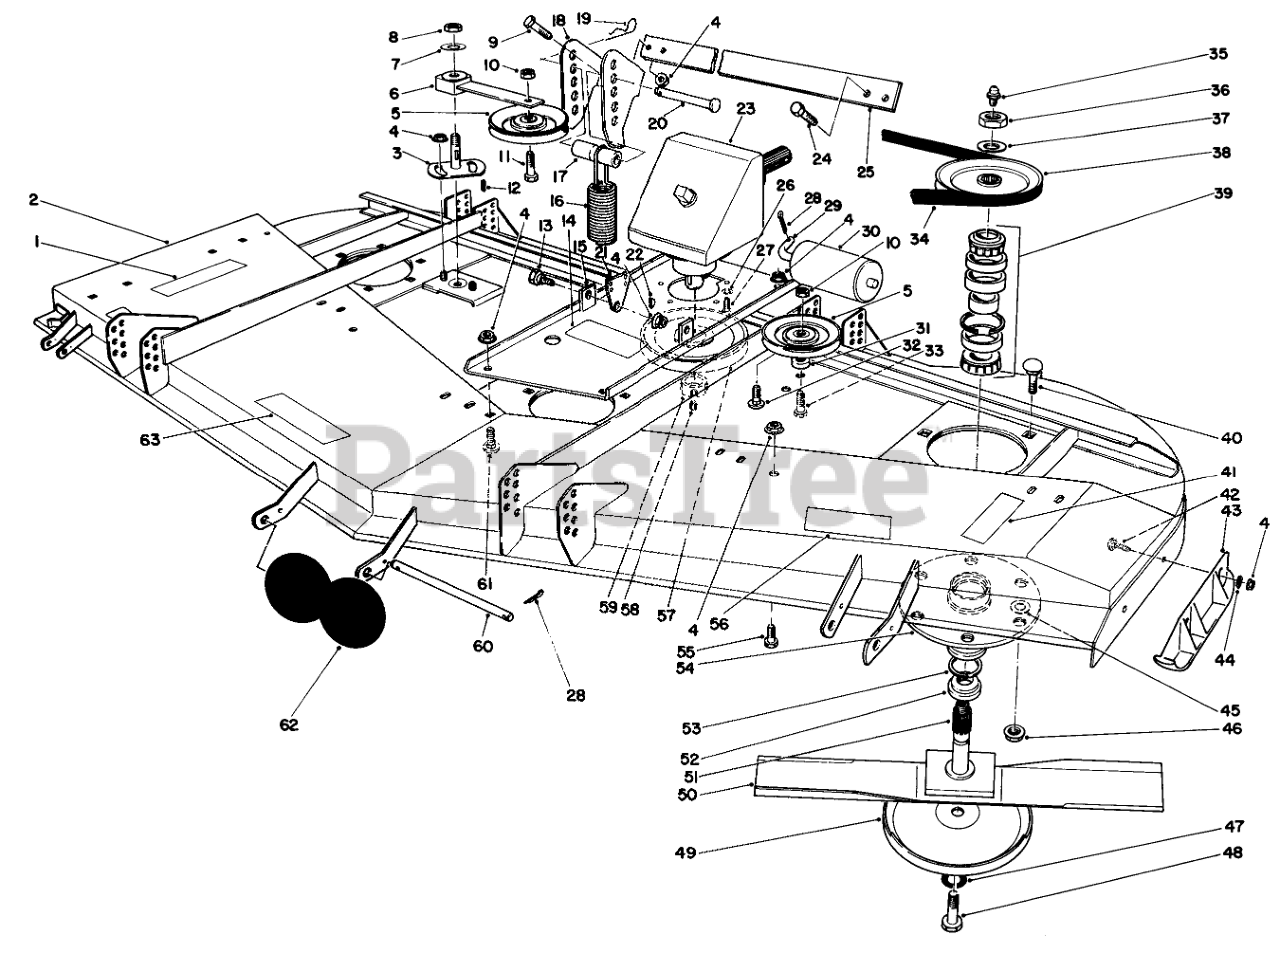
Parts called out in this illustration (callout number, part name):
1	DECAL-CAUTION, DEFLECTOR
2	62 DECK WA R
3	PLATE-IDLER
4	NUT-HHF, WHIZ
5	Pulley
6	IDLER ARM ASM
7	WASHER-FLAT
8	NUT-LOCK, NI
9	SCREW-HH
10	NUT-HEX
11	SCREW-HH
12	KEY-SQUARE
13	BOLT-SHOULDER
14	Decal-Caution
15	GEARBOX BASE WA R
16	Spring-Extension
17	SPACER
18	SPRING BRACKET R
19	PIN-HAIR
20	PIN-CLEVIS
21	SPRING END R
22	KEY-WOODRUFF
23	GEAR BOX ASM
24	SCREW-HH
25	BRKT MOUNT R
26	WASHER-LOCK
27	SCREW-HSH
28	PIN-COTTER
29	SHAFT-ROLLER, REAR
30	ROLLER-DECK
31	SPACER
32	SCREW-CARR
33	SCREW-HH
34	V-BELT
35	FITTING-GREASE
36	NUT-HEX
37	WASHER
38	PULLEY AND HUB ASM
39	BEARING ASM
40	SCREW-CARR
41	DECAL-CAUTION, BLADE
42	SCREW-CARR
43	Skid
44	LOCKWASHER-PYRAMID
45	WASHER-FLAT
46	NUT-HF
47	WASHER-LOCK
48	SCREW-BLADE
49	Cup-Scalp
50	Blade
51	SHAFT
52	SPACER
53	SEAL-OIL
54	HOUSING-SPINDLE
55	SCREW-HH
56	Decal-Rear Weight
57	PULLEY WA BO
58	SCREW-SET, HSH
59	BUSHING-LOCK, TAPER
60	SHAFT-ROLLER
61	SCREW-CARR
62	ROLLER
63	Decal-Caution
